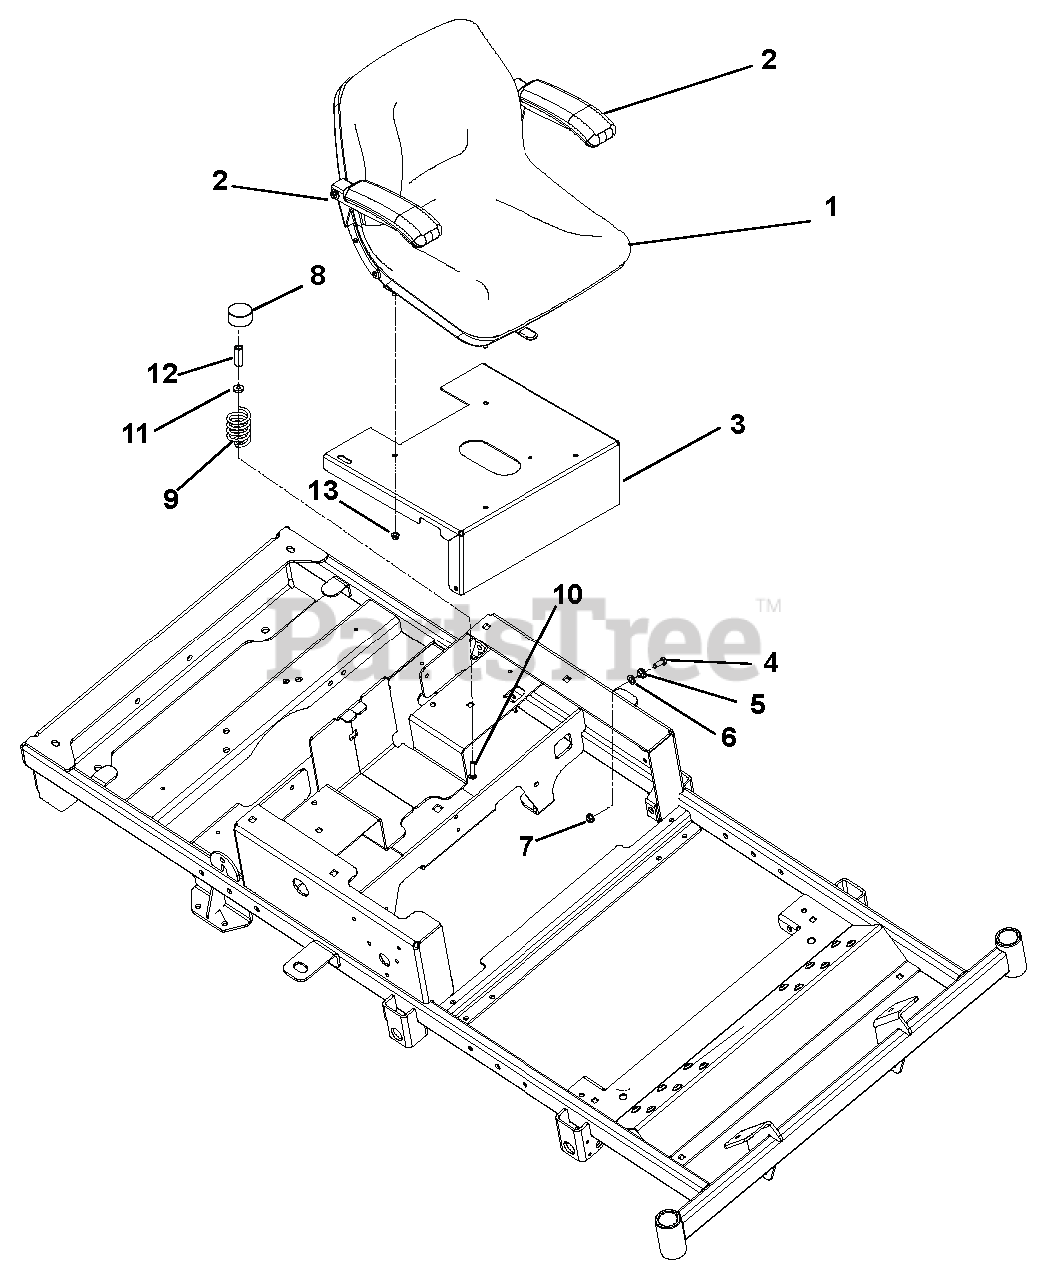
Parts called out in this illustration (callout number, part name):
1	SEAT, MILSCO XB-180
2	KIT, SEAT ARM RESTS
3	SEAT PLATE
4	@BLT-HEX .38-16X1.00 GR5 YWZC
5	BSHG-FLG .385X.500X.875X.406
6	WSHR-FL-STL .52X.827X.062 YWZC
7	@NUT-LK-NYL-FLG .38-16 YWZC
8	HUB CAP
9	SPRING, SEAT
10	@BLT-RDHDSQNK .31-18X1.50 G5YZ
11	WSHR-FL-STL .328X.87X.179 YWZC
12	NUT, COUPLING 5/16-18 X 1 3/4
13	@NUT-LK-NYL-FLG .31-18 YWZC
